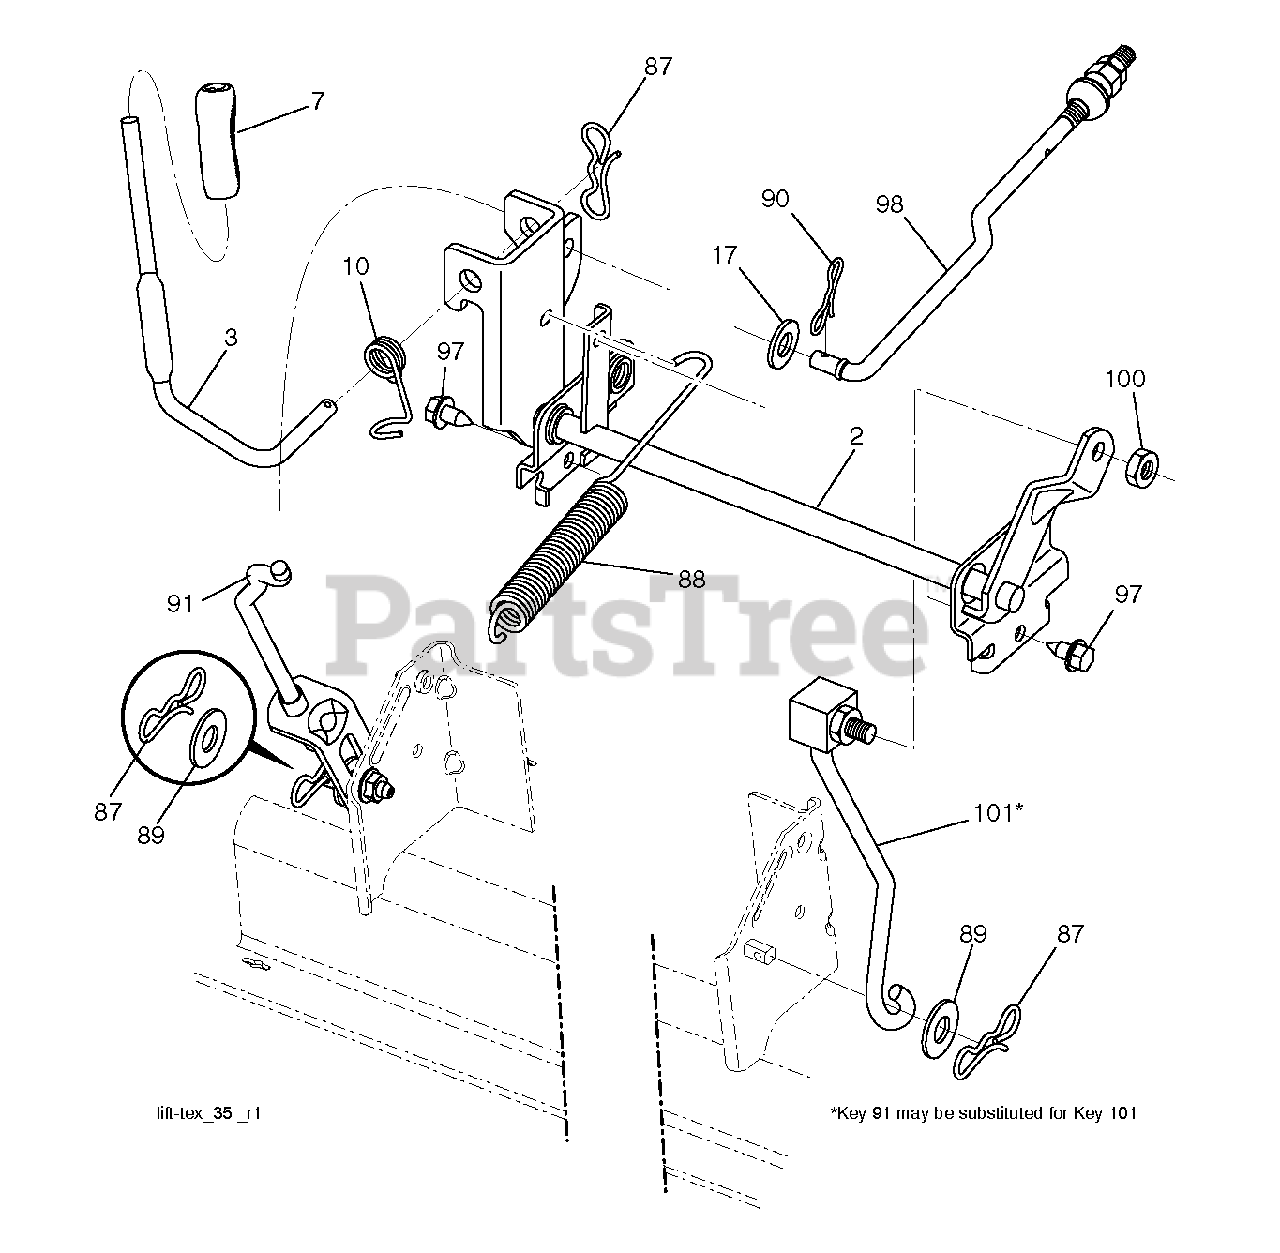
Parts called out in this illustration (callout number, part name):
2	SHAFT.ASM.CROSS.LIFT
3	LEVER.LIFT.HANDLE.LT
7	GRIP.HANDLE.LIFT.PVC.BLACK
10	SPRING.TORSION.LIFT.HANDLE
17	WASHER
87	PIN.COTTER.7/16.BOW TI.
88	SPRING.LIFT.ASSIST
89	WASHER.CLEAR.ZINC
90	PIN.COTTER.5/16.BOW TI
91	LINK.ASM.LIFT.REAR
97	SCREW, 3/8-16X3/4
98	LINK.ASM.SUSP.FRONT.MW
100	LOCKNUT
101	LINK.ASM.LIFT.FIXE.38/42/46"
